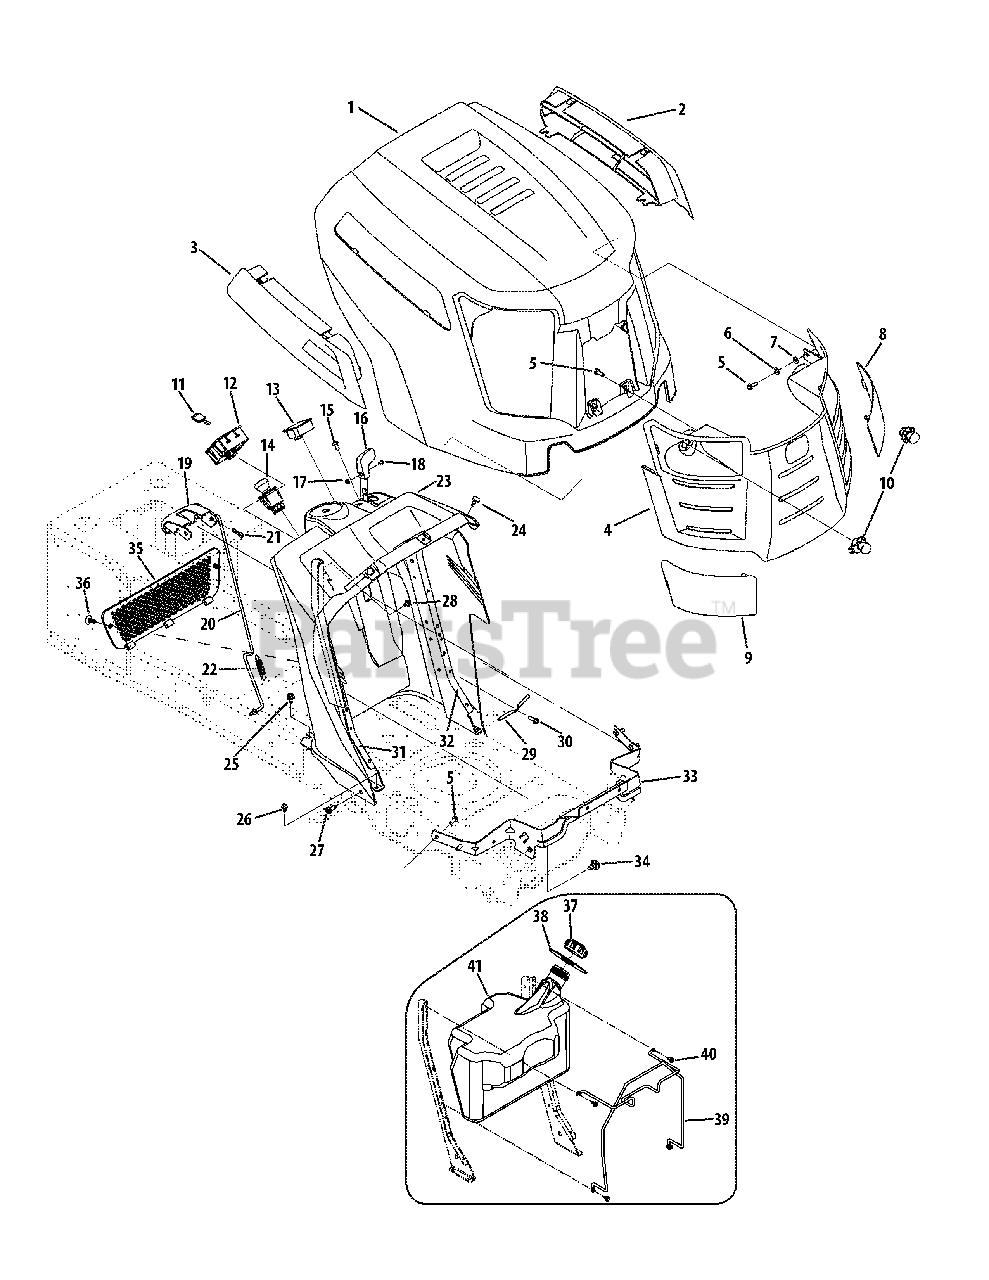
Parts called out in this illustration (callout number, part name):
2	LH Hood Scoop
3	RH Hood Scoop
4	Grille Asm
5	Hex Washer BosScrew™, 1/4 Dia. x .750
6	Flat Washer, .271 x .630 x .065
7	Lock Washer, 1/4
8	Lens, LH
9	Lens, RH
10	Bulb
10	Headlight Socket
11	Key
12	Key Switch
13	Indicator Meter
14	Electric PTO
15	Screw, 1.4-14 x .625
16	Throttle Knob
17	Hex Nut, #8-32
18	Screw, #8-32 x .375
19	Parking Brake/Cruise Control Lever
20	Control Rod
21	Bow-Tie Cotter Pin
22	Extension Spring, .500 x 2.733
23	Dash Panel
24	Bumper
25	Hex Washer Screw, 5.16-18 x .750
26	Hex Washer Screw, 1.4-20 x .500
27	Screw, 5.16-18 x .750
28	Hex Washer Screw, 1.4-20 x .625
29	Bent Lever Rod
30	Hex Washer Screw, 1.4-15 x .750
31	Dash Support, RH
32	Dash Support, LH
33	Hood Pivot Bracket
34	Shoulder Screw, 5.16-18 x .43 x .29
36	Ratchet Clip
37	Fuel Cap
38	Fuel Tank Gasket
39	Fuel Tank Support Rod
40	Hex Washer Screw, 1.4-20 x .625
41	Fuel Tank
